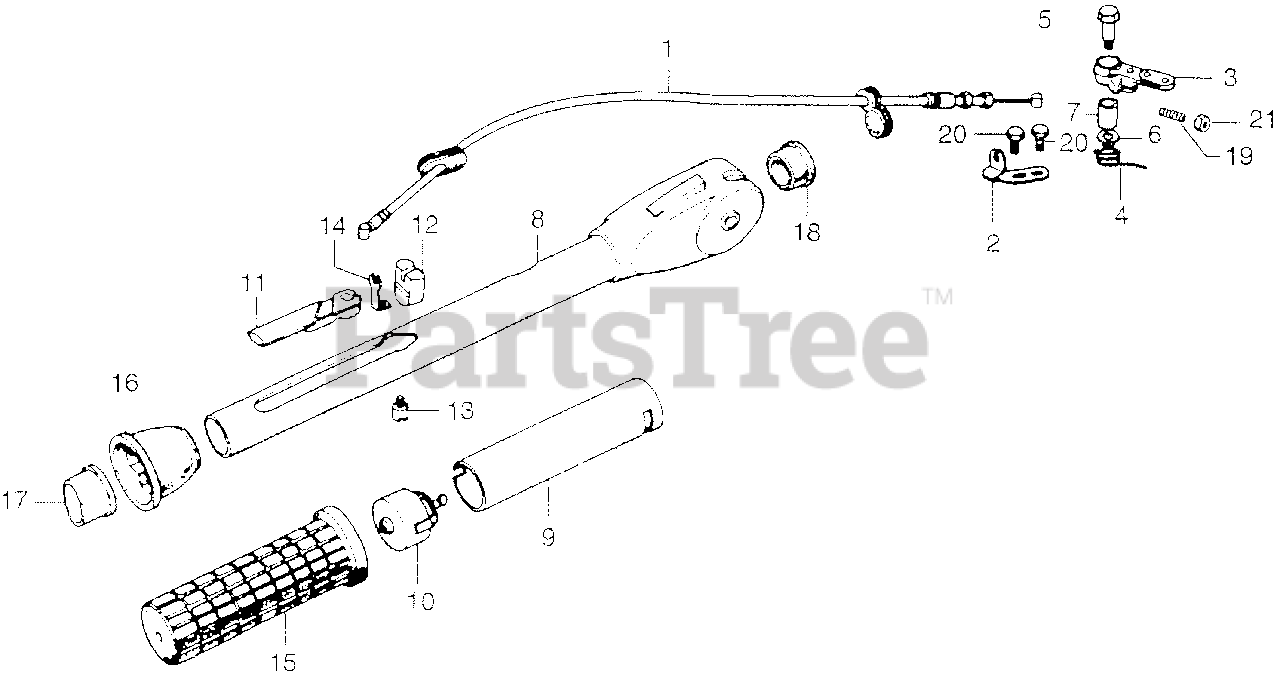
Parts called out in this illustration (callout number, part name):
1	CABLE, THROTTLE (NOT AVAILABLE)
2	HOLDER, CABLE
3	ARM, THROTTLE (NOT AVAILABLE)
4	SPRING, THROTTLE ARM
5	PIVOT, THROTTLE
6	WASHER, PIVOT
7	BUSHING, PIVOT (NOT AVAILABLE)
8	HANDLEBAR *PB1* (DARK BLUE) (NOT AVAILABLE)
9	PIPE, GRIP
10	NUT, GRIP FRICTION (NOT AVAILABLE)
11	HINGE, THROTTLE WIRE
12	HOLDER, THROTTLE CABLE (NOT AVAILABLE)
13	STOPPER, GRIP PIPE
14	STOPPER, CABLE
15	RUBBER, GRIP (NOT AVAILABLE)
16	COVER, GRIP PIPE
17	GUIDE B, GRIP PIPE
18	PLUG, HANDLEBAR (NOT AVAILABLE)
19	SCREW, THROTTLE ADJUST
20	BOLT, HEX. (6X12)
21	NUT, HEX. (5MM)
